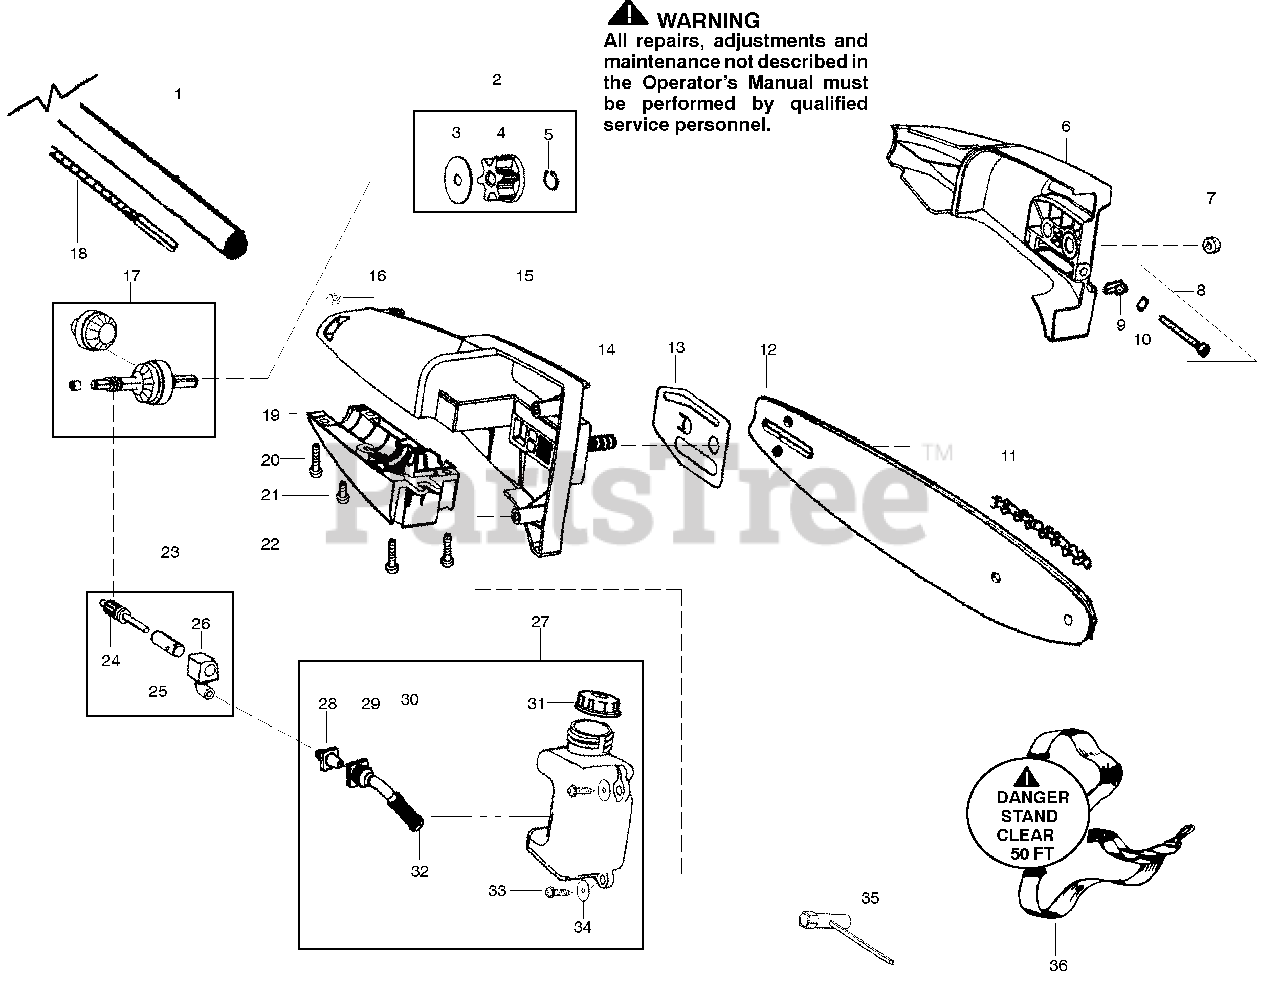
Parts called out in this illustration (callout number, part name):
1	Assy-Driveshaft
2	Kit-Sprocket Assy.
4	Sprocket
5	Retainer-Sprocket
6	Assy-Bar Clamp
7	Nut-Bar Mounting
8	Kit-Bar Adjust
9	Pin-Bar Adjust
10	Retainer-Bar Adjust
11	Chain-8"
13	Plate-Bar pad
14	Bolt-Bar
15	Hsg.-Upper
17	Kit-Gear Assy
18	Flex shaft - lower
19	Hsg.-Lower
21	Screw-Align
23	Kit-Oil Assy
24	Assy-Gear Plunger
26	Block-Oil
27	Assy-Oil Tank
28	Fitting-Oil Line
29	Intake-Oil Line
30	Filter-Oil
31	Cap-Oil
32	Plug-Oil Filter
35	Wrench-Bar
36	Strap-Shoulder
